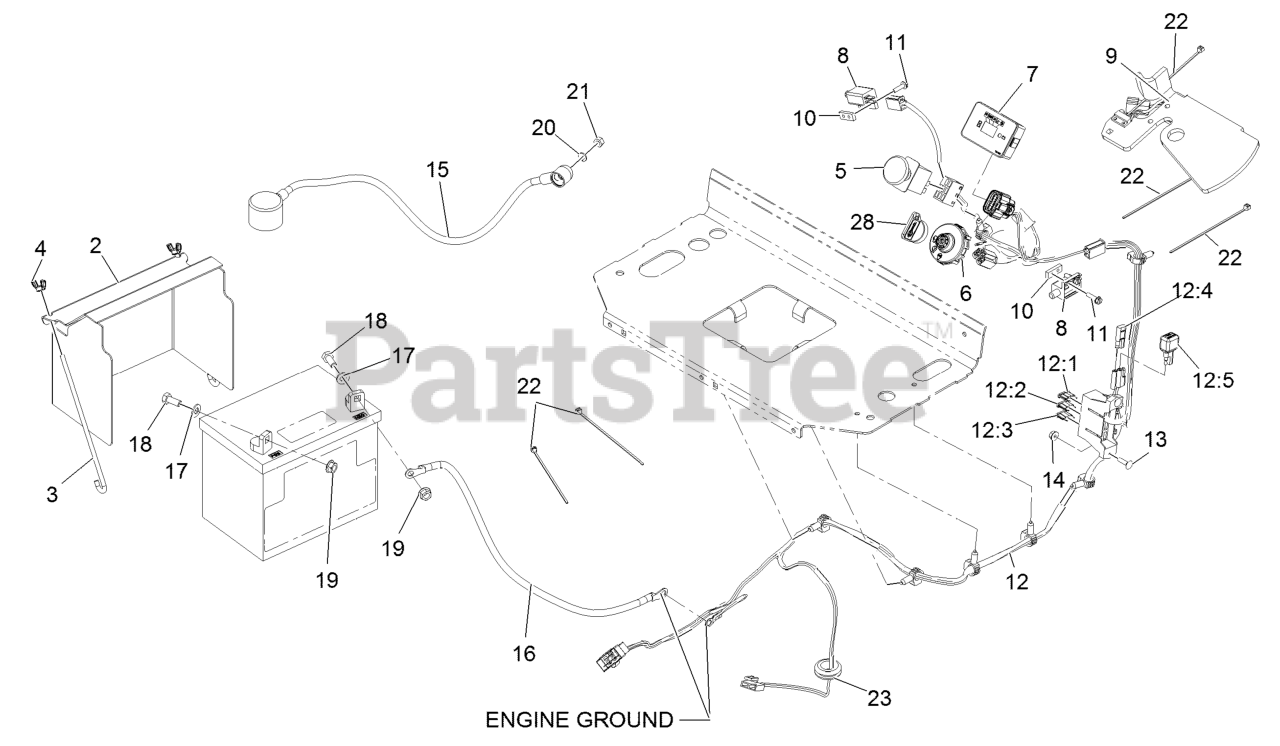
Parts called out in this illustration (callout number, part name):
2	COVER-BATTERY
3	BOLT-HOLDDOWN
4	WINGNUT
5	SWITCH-PTO, ON-ON
7	MODULE-HOUR METER
8	SWITCH-CLOSED, NORMALLY
9	HARNESS-SWITCH, REED
10	PLATE-TAPPED
11	SCREW-HWH
12	HARNESS-WIRE
12:1	FUSE-BLADE, 30 AMP
12:2	FUSE-BLADE, 25 AMP
12:3	FUSE-BLADE, 10 AMP
12:4	CAP-PLUG
13	SCREW-CARR
15	CABLE-BATTERY, POSITIVE
16	CABLE-BATTERY, BLACK
17	WASHER-PLAIN
18	SCREW-HH
19	NUT-HHF, SMOOTH
20	SCREW-HH
21	NUT-HEX
22	TIE-CABLE
23	GROMMET
28	KEY-IGNITION
